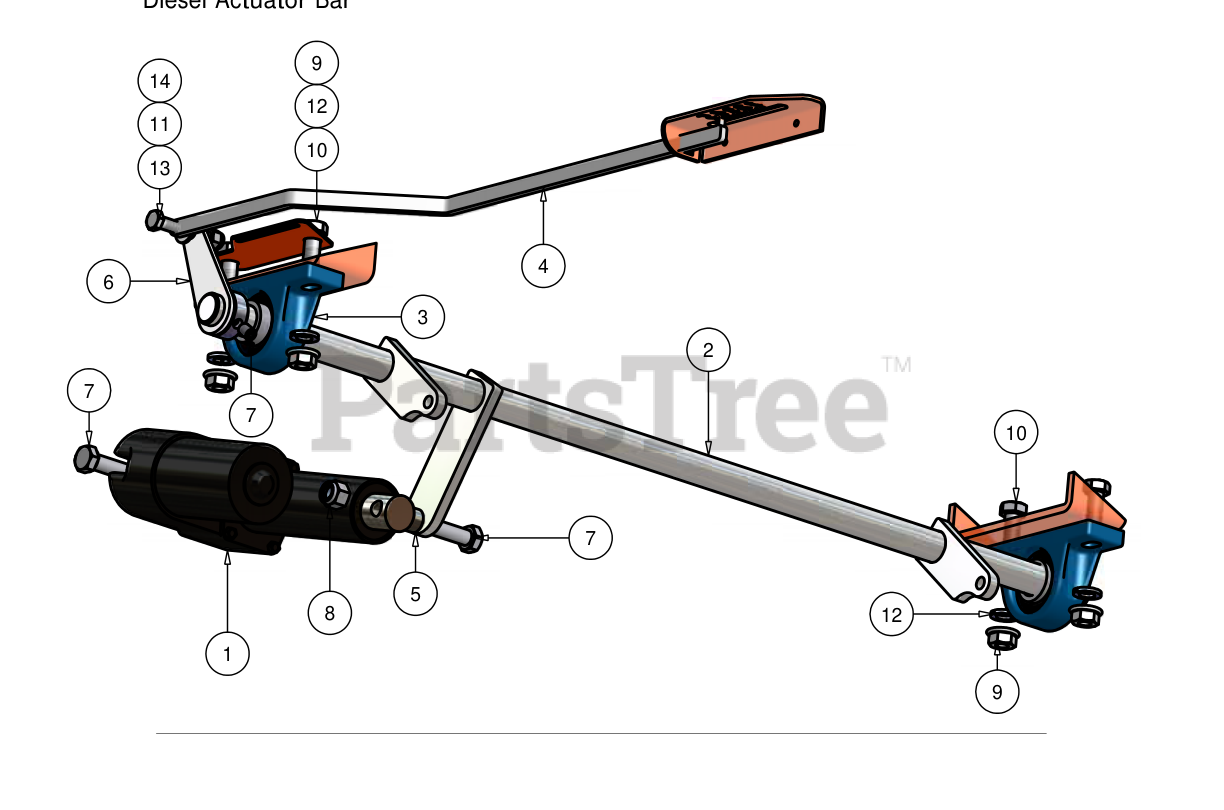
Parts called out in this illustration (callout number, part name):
2	Actuator Bar
3	1" Pillow Block
4	Height Indicator
5	1/2" Washer
6	2006 Height Indicator Lever
7	1/2" x 2 1/2" Hex Bolt
8	1/2" Nylock Nut
9	1/2" Flange Nut
10	1/2" x 1 1/2" Hex Bolt
11	.360 ID Plastic Washer
12	1/2" Lock Washer
13	3/8" x 1" Hex Bolt
14	3/8" Nylock Nut
